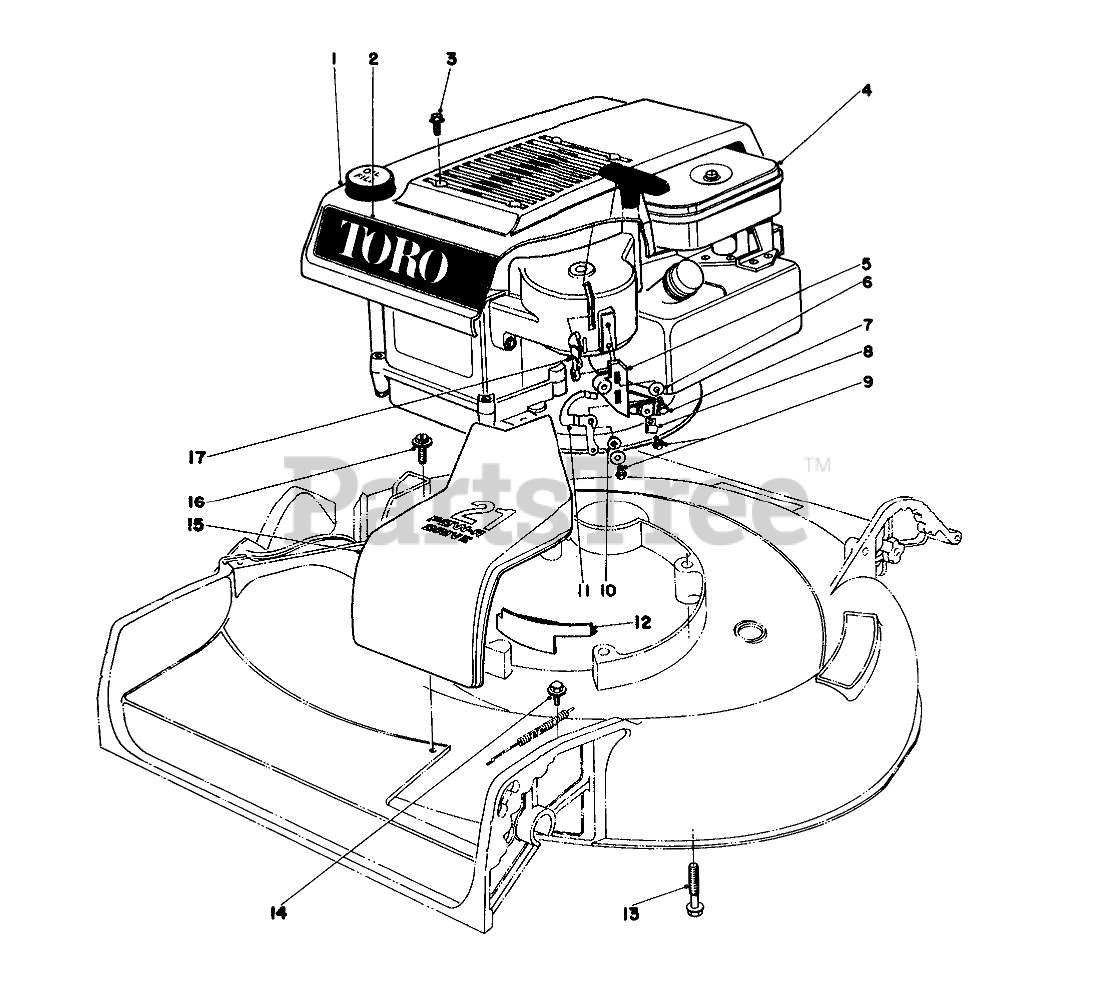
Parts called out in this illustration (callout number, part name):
1	Shroud
2	Decal-Toro
3	8X1/2 SELF TAP SCREW
4	Engine
5	CABLE & PIVOT BLOCK
6	WASHER-FLAT
7	SCREW-SHWH
8	CLAMP
9	SCREW-HWHTF
10	BUSHING
11	CAM INTERLOCK
12	HOUSING CAP
13	3/8-16 X 2-3/4 CAPSCR
14	SCREW-HWHTF
15	BELT DRIVE COVER
16	SCREW
17	INTERLOCK LEVER
